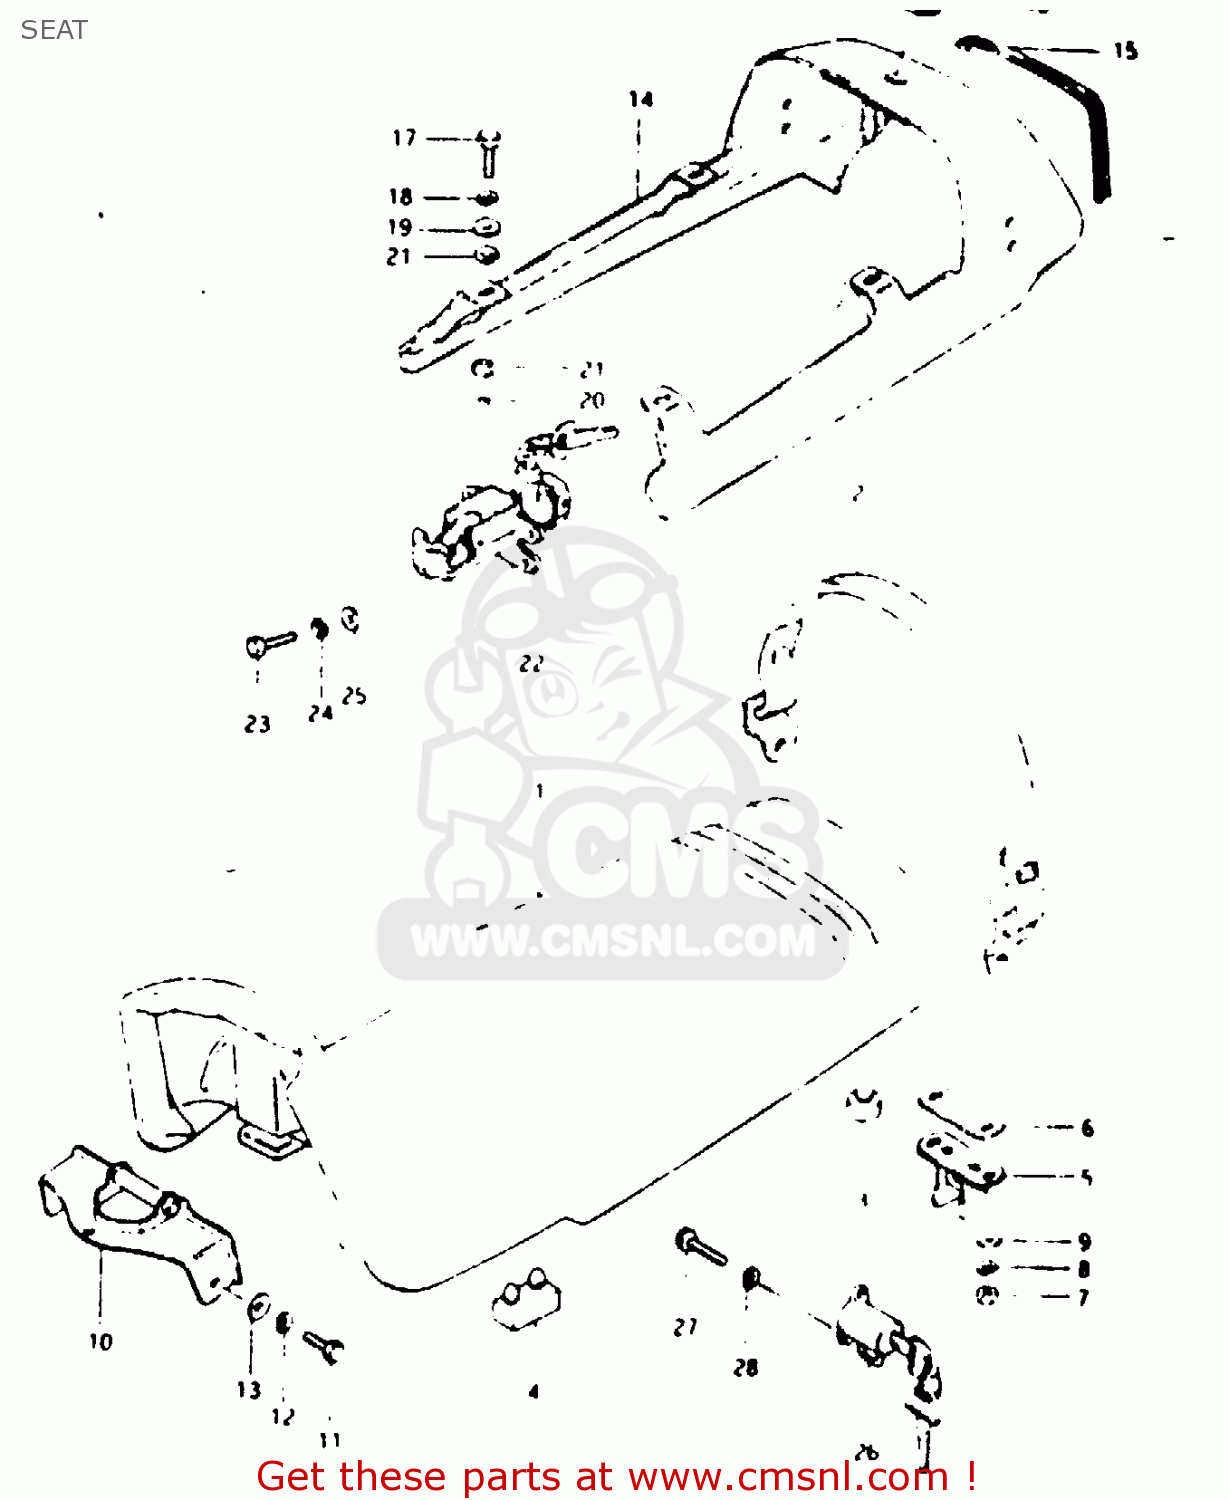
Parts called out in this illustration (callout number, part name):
1	SEAT ASSY
3	CUSHION
4	CUSHION
5	STRIKER,SEAT LOCK
6	SHIM,SEAT LOCK STRIKER
7	NUT 6MM
8	LOCK WASHER
9	WASHER
10	PLATE,SEAT HOOK FR
11	BOLT
12	LOCK WASHER
13	WASHER
14	COVER,SEAT TAIL
15	MOLD, SEAT TAIL
16	GROMMET,SEAT LOCK HOLE
17	BOLT
18	LOCK WASHER
19	WASHER (6.5X24X1.6)
20	SPACER (7X10X12)
21	CUSHION
22	LOCK SET
23	BOLT
24	LOCK WASHER
25	WASHER
26	LOCK ASSEMBLY,HELMET
27	BOLT
28	LOCK WASHER
